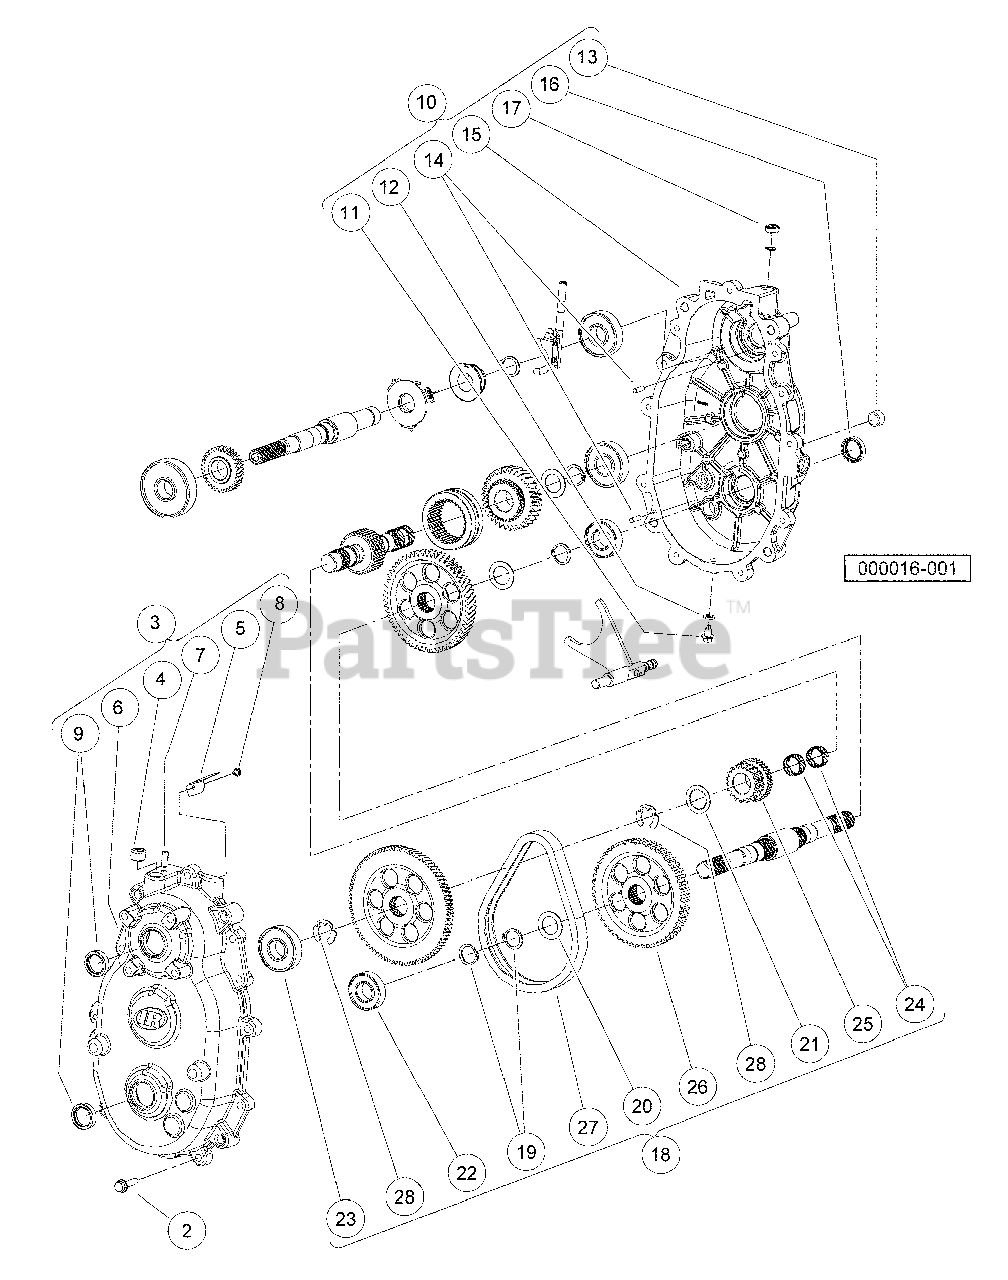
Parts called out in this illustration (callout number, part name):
1	Transmission, Parallel Shaft
2	Screw,hex Flange, M8 X 35
3	Asm, Gear Case, Rear
4	Plug, Square Skt, 1/12-14, Ptf
5	Oil, Deflector
6	Gearcase, Rear
7	Vent, Trans
8	Screw, Tapping # 10-24 X .375
9	Seal, Triple, 25 X 35 X 7.8
10	Asm, Gear Case, Front
11	Plug,3/8-16, Hex Flange
12	Washer, .625 X .382 X .60
13	Plug, Square Skt, 1/12-14, Ptf
14	Pin, Dowel, 6 X 20
15	Gearcase, Front
16	Seal, Triple, 25 X 35 X 7.8
17	Seal, Dual-Lip
18	Kit, Reverse Gear Repair
19	Ring, Retaining, Basic External
20	Washer, Thrust, 1.007 X .062
21	Washer, 26.231 X 39.167 X 1.57
22	Bearing, Ball
23	Bearing, Ball
24	Bearing, Needle
28	Ring, Retaining, E-Ring
